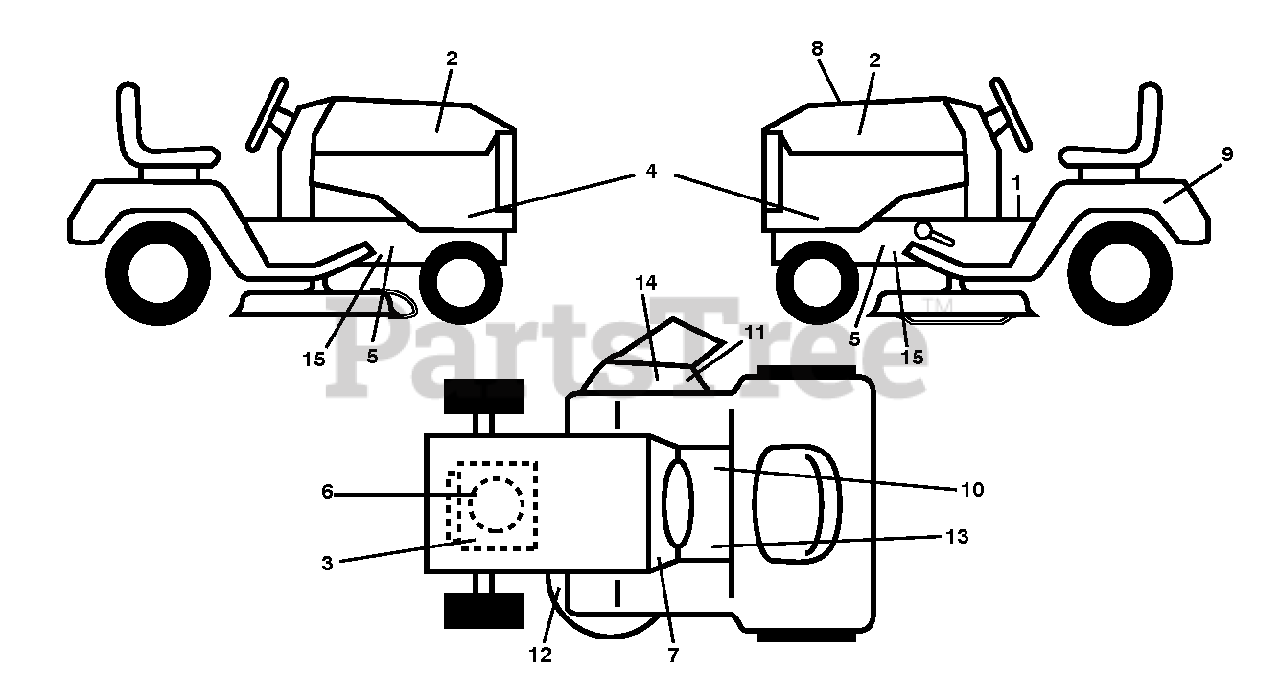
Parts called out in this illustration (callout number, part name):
1	DECAL.READ.OWN.MAN.SYMBOL.LT
2	DECAL.BADGE.170MM.TEXTLOGO.
3	DECAL.ENGINE.WARNING
4	DECAL.SDPNL.HUSQLT.TS238
5	DECAL.CHASSIS.HOT.MUFFLER
6	DECAL.ENG.BS.500CC.ENDR.382273
7	DECAL.SNOWFLAKE.MS498.HUSQ
8	DECAL.RPL.BSM31.HS.TLW.97.K46
9	DECAL BTRY SYMBOLS
10	DECAL.PARKING.BRAKE.SADDLE.LT
11	DECAL.DFLCTR.WARNNG.CTFNGR.SYM
12	DECAL.DECK.SCH.36,38,94.NONCR
13	DECAL.FNDR.SDLE.BRAKE.CLUTCH.6
14	DECAL, DECK DEFLECTOR, WARNING
15	DECAL.WARNING.SERVCE/FIRE
